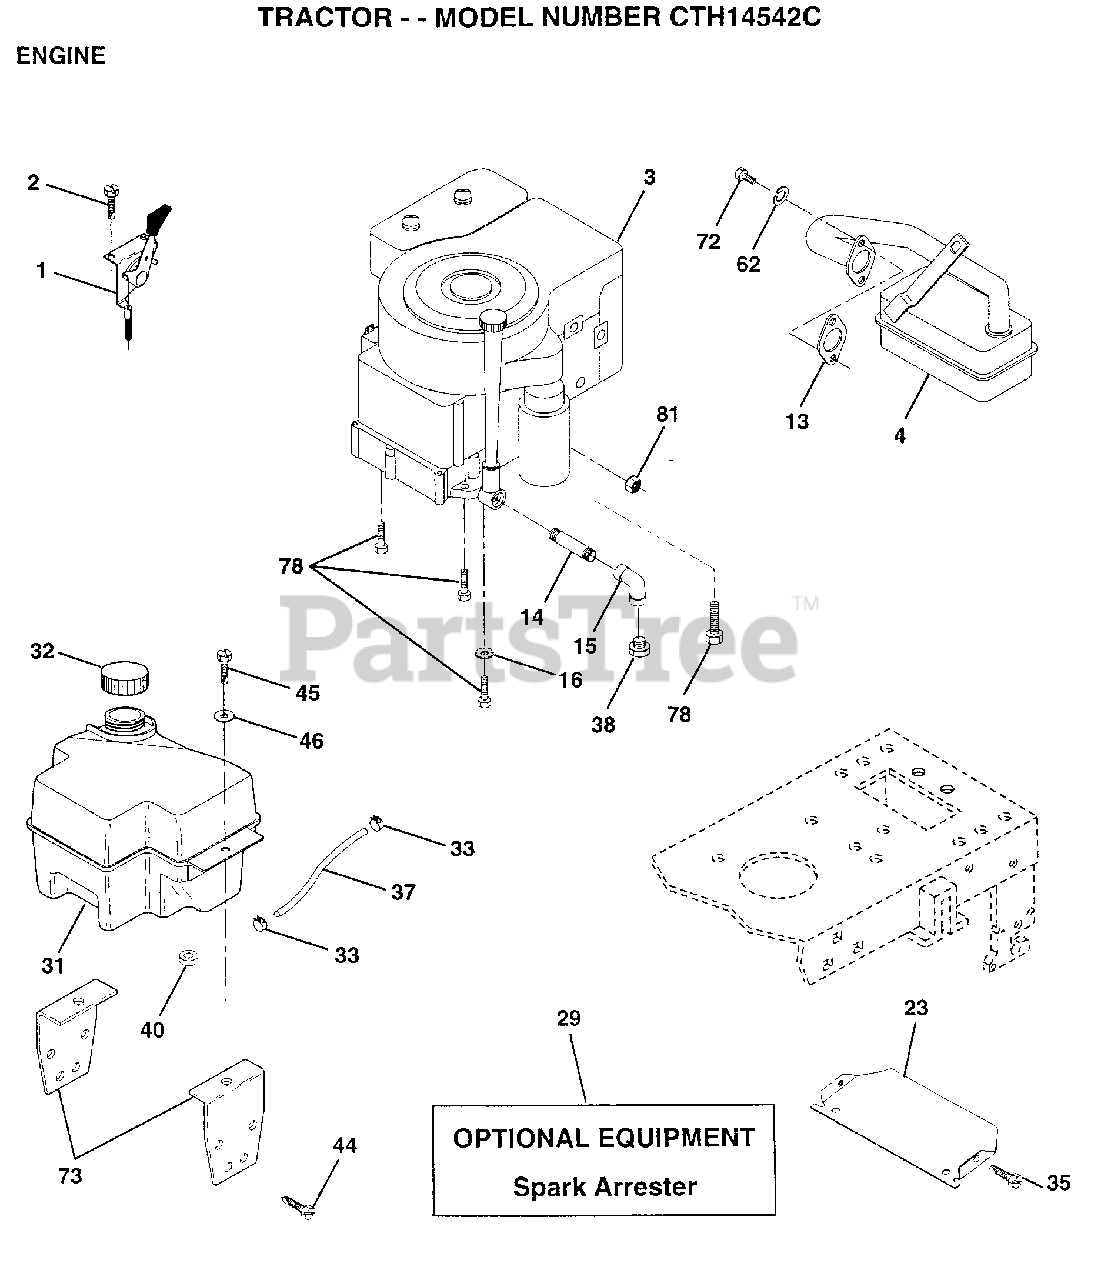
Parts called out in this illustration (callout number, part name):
1	CONTROL.THTL.19.6
2	SCREW LT
4	MUFFLER
13	GASKET ENG 1 313 LD TIN PLATED
14	PIPE NIPPLE
15	ELBOW
16	LOCKWASHER
32	CAP ASM FUEL
33	HOSE CLAMP
35	SCREW
37	LINE FUEL
44	SCREW
45	SCREW HEX CRT
46	WASHER
62	LOCKWASHER
72	SCREW
73	BRACKET.SUPT.TANK
78	SCREW
81	NUT
